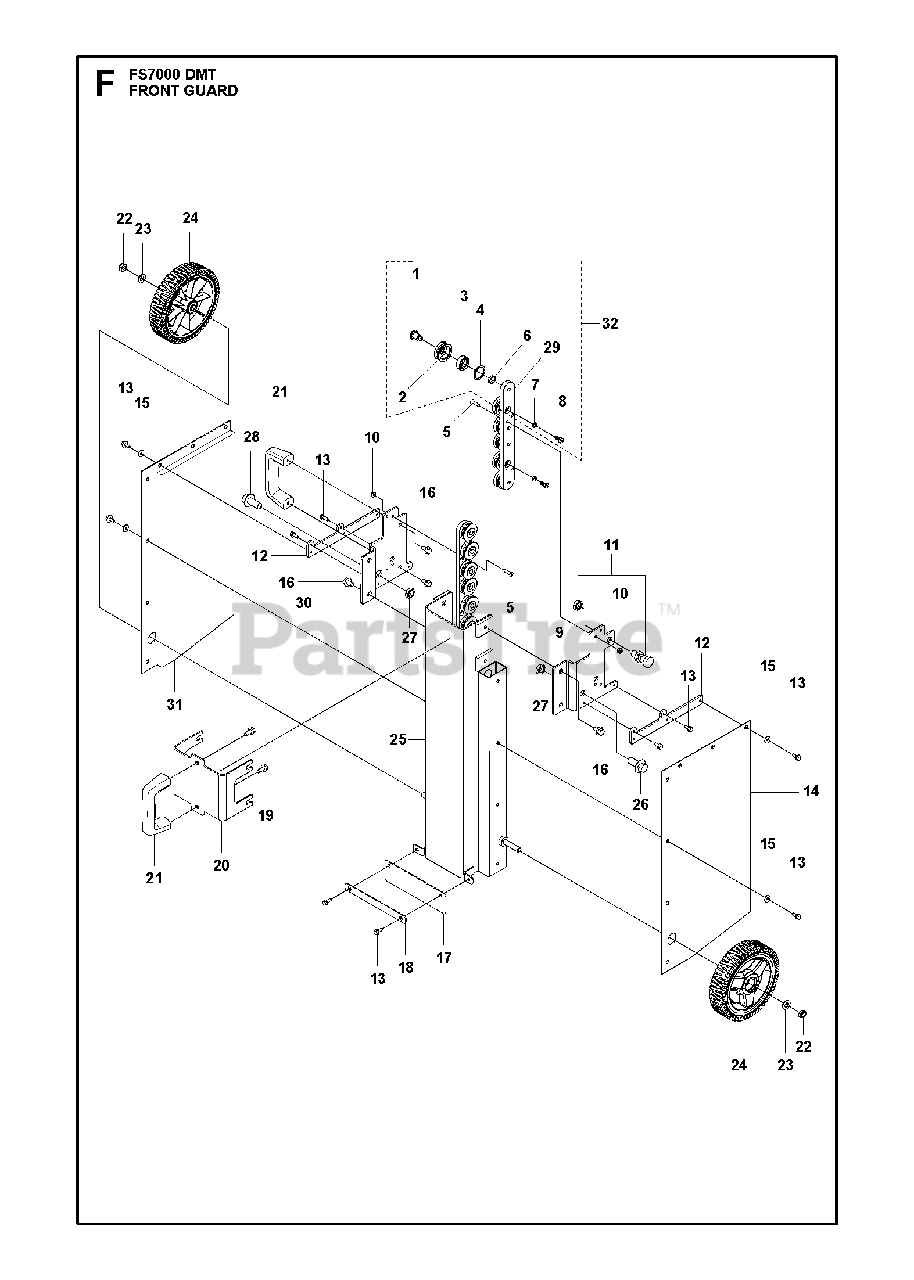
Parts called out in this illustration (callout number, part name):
10	HEXAGON NUT FLANGE
23	WASHER
24	WHEEL & TIRE ASSY, FRONT
27	HEXAGON THIN NUT
